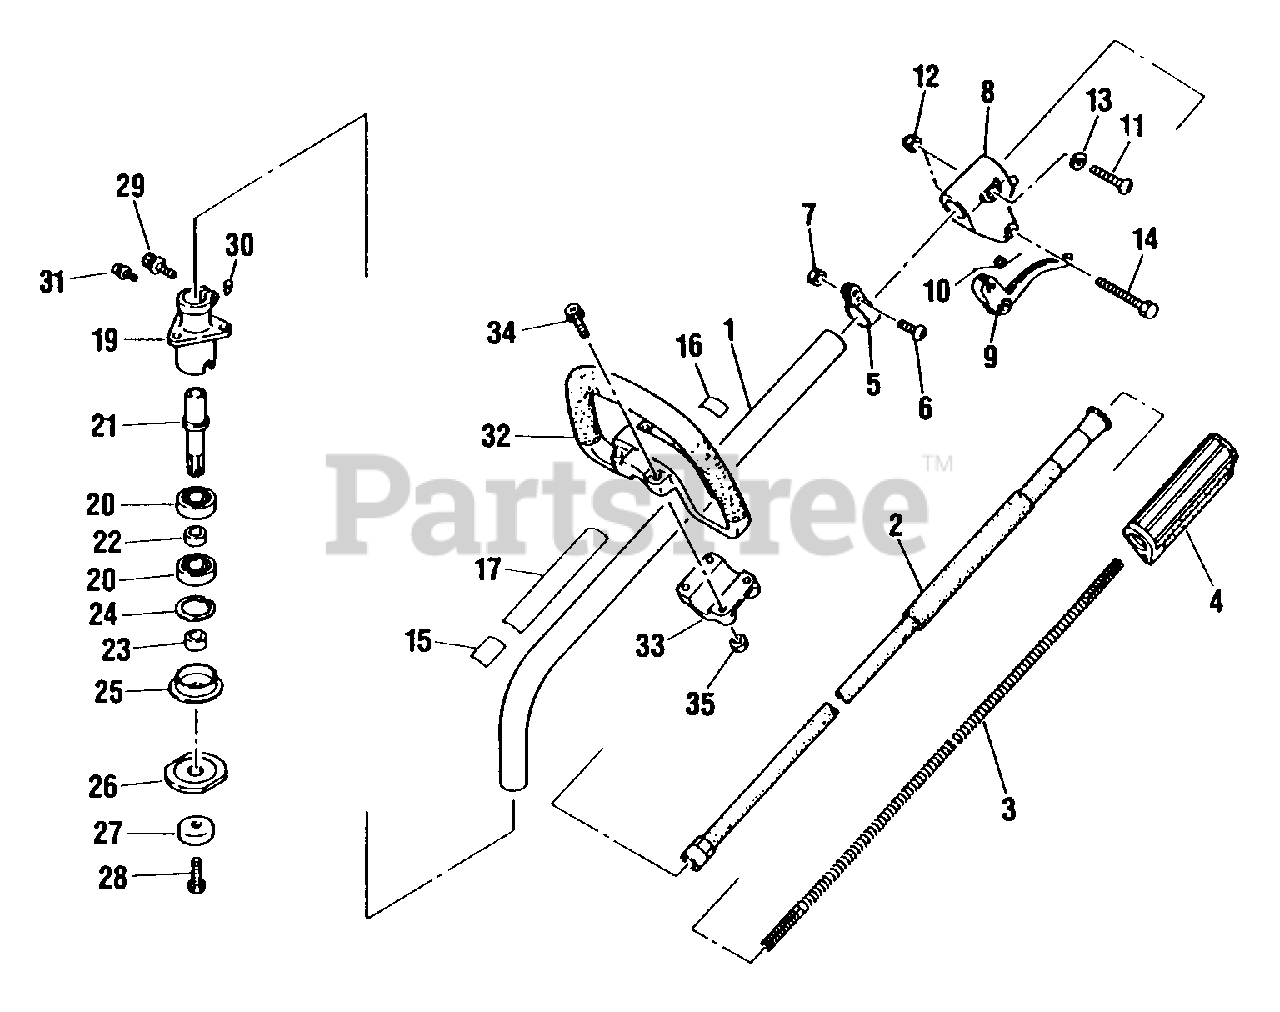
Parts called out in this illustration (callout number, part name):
2	LINER - FLEXIBLE
3	DRIVESHAFT - FLEXIBLE
4	GRIP
5	HANGER
6	SCREW M5×12
7	NUT M5
8	BODY
9	LEVER
10	SCREW
11	SCREW
13	WASHER, FLAT 5.5×10×0.8
14	BOLT
15	LABEL, CAUTION
16	LABEL, HANDLE
17	LABEL - MODEL
19	HOUSING, GEAR CASE
20	BEARING, BALL 6001 DDU
21	SHAFT
22	COLLAR (A)
23	COLLAR (B)
24	RING, SNAP Ø28
25	HOLDER (A)
26	HOLDER (B)
27	GUARD, BOLT
29	BOLT M5×25
30	D-WASHER
31	BOLT
33	LOWER CAP
34	BOLT
35	NUT M5
